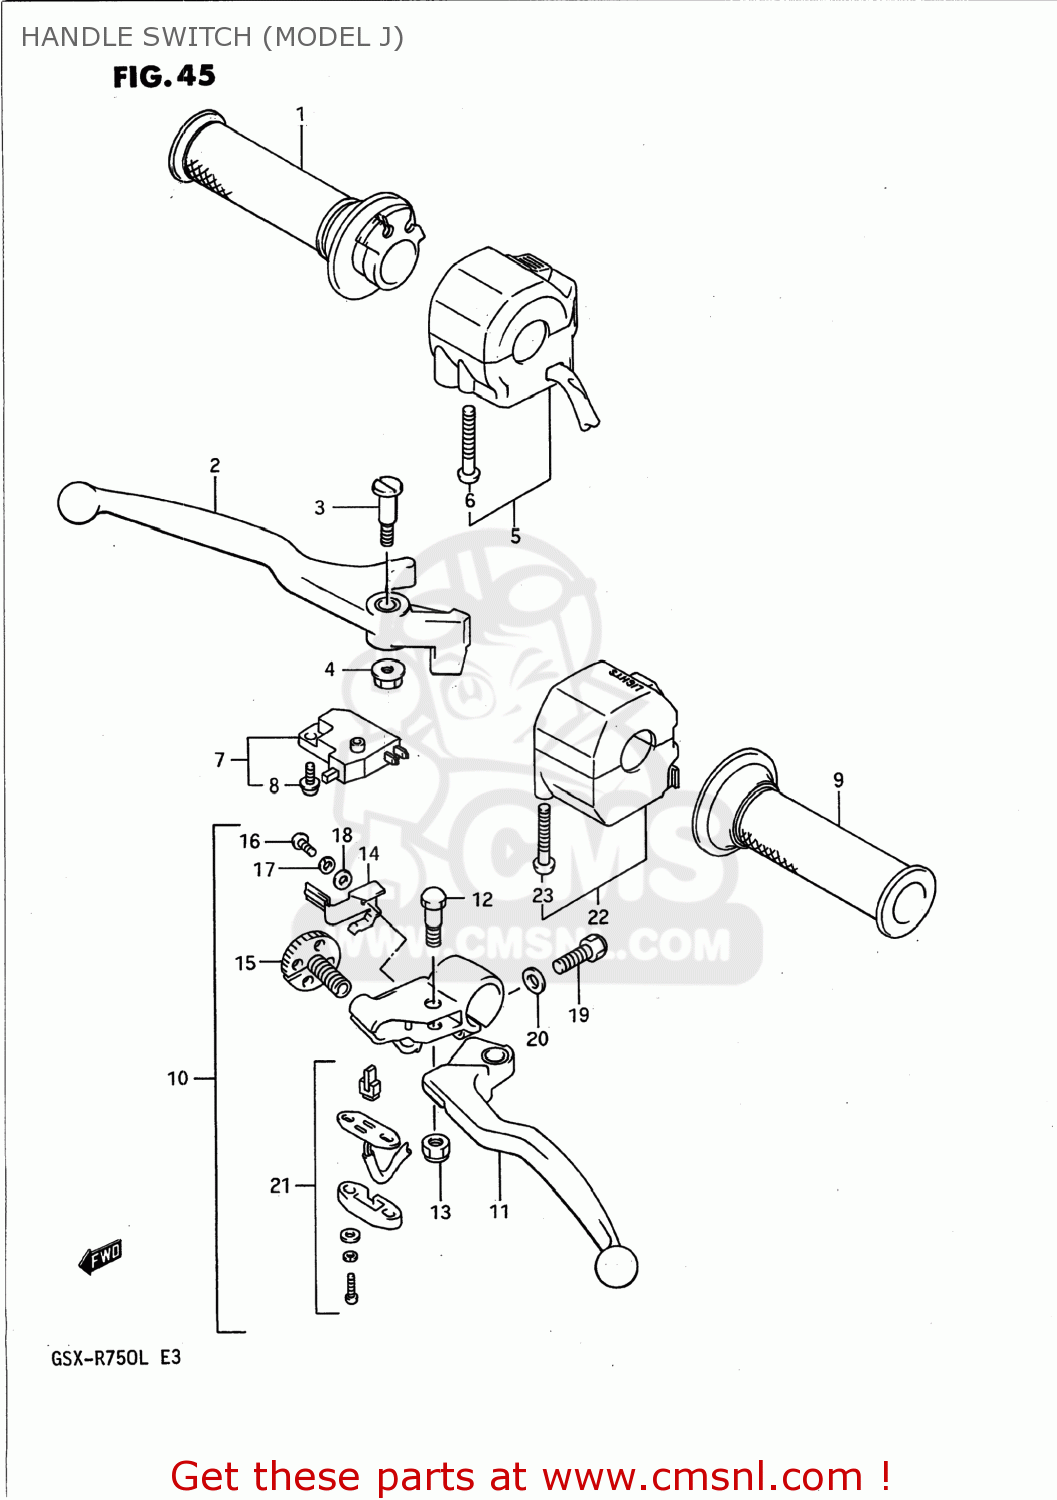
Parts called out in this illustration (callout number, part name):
1	GRIP,THROTTLE
2	LEVER,BRAKE
3	BOLT,LEVER PIVOT
4	NUT 6MM
5	SWITCH ASSEMBLY,HANDLE,RIGHT
6	SCREW, 5X45
7	SWITCH ASSEMBLY,STOP
8	SCREW
9	GRIP,L
10	LEVER ASSEMBLY
11	LEVER,CLUTCH
12	BOLT,LEVER PIVOT
13	NUT
14	ADJUST,SPRING
15	ADJUSTER,LOCK
16	SCREW 4X6
17	WASHER,LOCK 4M
18	WASHER 4MM
19	BOLT
20	WASHER
21	SWITCH ASSEMBLY,CLUTCH
22	SWITCH ASSEMBLY,HANDLE,LEFT
23	SCREW, 5X45
